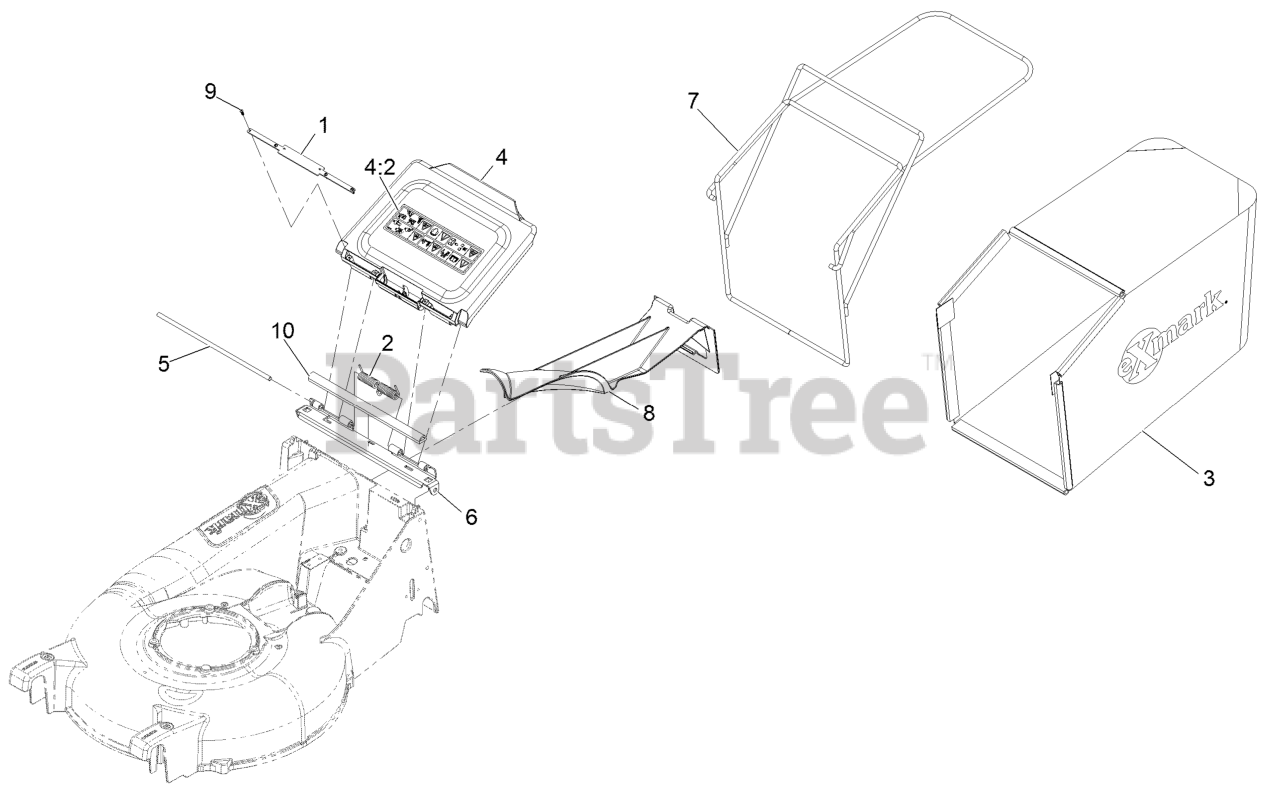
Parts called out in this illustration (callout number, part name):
1	PLATE, DOOR COVER
2	SPRING-PLASTIC DOOR
3	BAG-21 GRASS
4	ASM-DOOR & DECAL
4:2	DECAL-WARNING
5	PIN-DOOR PIVOT
6	BRACKET-DOOR PIVOT
7	WLD-BAG FRAME
8	PLUG,MULCH
9	SCR,TAP,6-19X7/16,PHPH, S
10	SEAL-EPDM FOAM BULB
